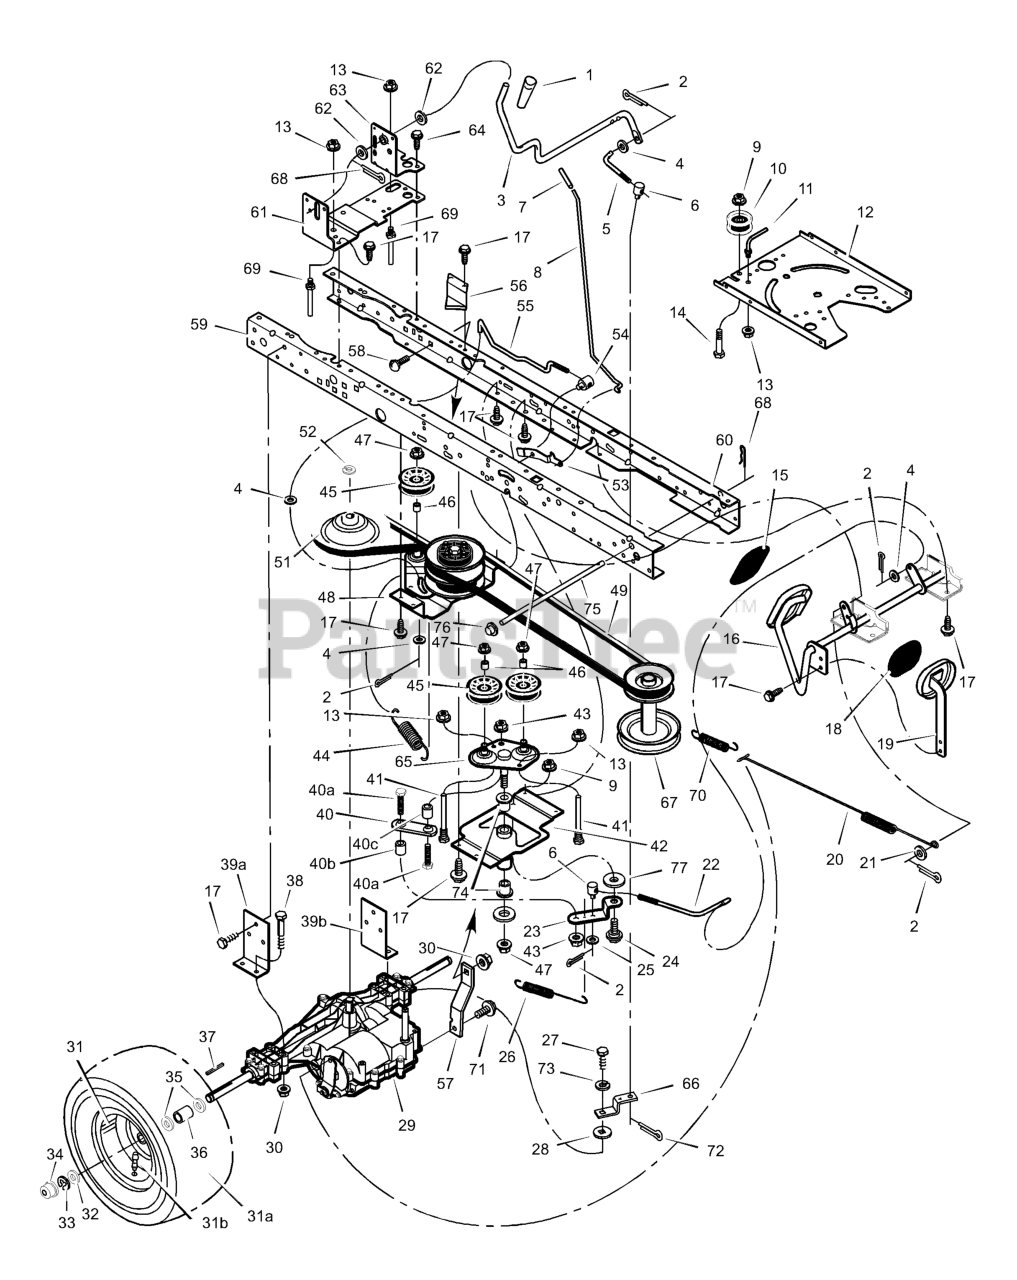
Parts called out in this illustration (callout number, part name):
1	Grip
2	Pin, Cotter
3	Lever, Shift
4	Washer
5	Link, Shifter
6	Nut, Adjuster
8	Rod, Parking Brake
9	Nut
10	Pulley, Idler
11	Guide, Belt
12	Plate, Steering
13	Nut
14	Bolt, Hex
15	Pad, Motion Drive
16	Assembly, Speed Control
17	Screw, Self Tapping
18	Pad, Brake Pedal
19	Assembly, Brake Pedal
20	Spring, Extension
21	Washer
22	Rod, Speed Control
23	Bellcrank
24	Bolt, Shoulder
26	Spring, Extension
27	Screw, Cap
29	Transaxle
30	Nut
31	Assembly, Wheel and Tire
31B	Stem, Valve
36	Spacer
37	Key, Square
38	Bolt, Hex
39A	Bracket, Right Transaxle
39B	Bracket, Left Transaxle
40	Link, Variator
40A	Bolt, Hex
40B	Spacer, 1/2"
40C	Spacer, 3/4"
41	Guide, Belt
42	Bracket, Front Frame
43	Nut, Lock
44	Spring, Extension
47	Nut
48	Assembly, Variator and Idler
49	Belt, Primary
50	Belt, Secondary
51	Pulley, Transaxle
52	Ring, Snap
53	Latch, Parking Brake
54	Nut, Adjusting
55	Rod, Clutch
56	Bracket, Brake
57	BRACKET, Torque Strap, LH
58	Screw
59	Rail, Right Frame
60	Rail, Left Frame
61	Bracket, Right Shift
62	Washer
63	Bracket, Shift Pivot
65	Assembly, Idler
66	Yoke, Shift
67	Pulley, Stack
68	Pin, Hair
69	Guide, Belt
70	Spring, Return
72	Pin, Hair
75	Rod, Belt Guide
76	Nut, Push-On
